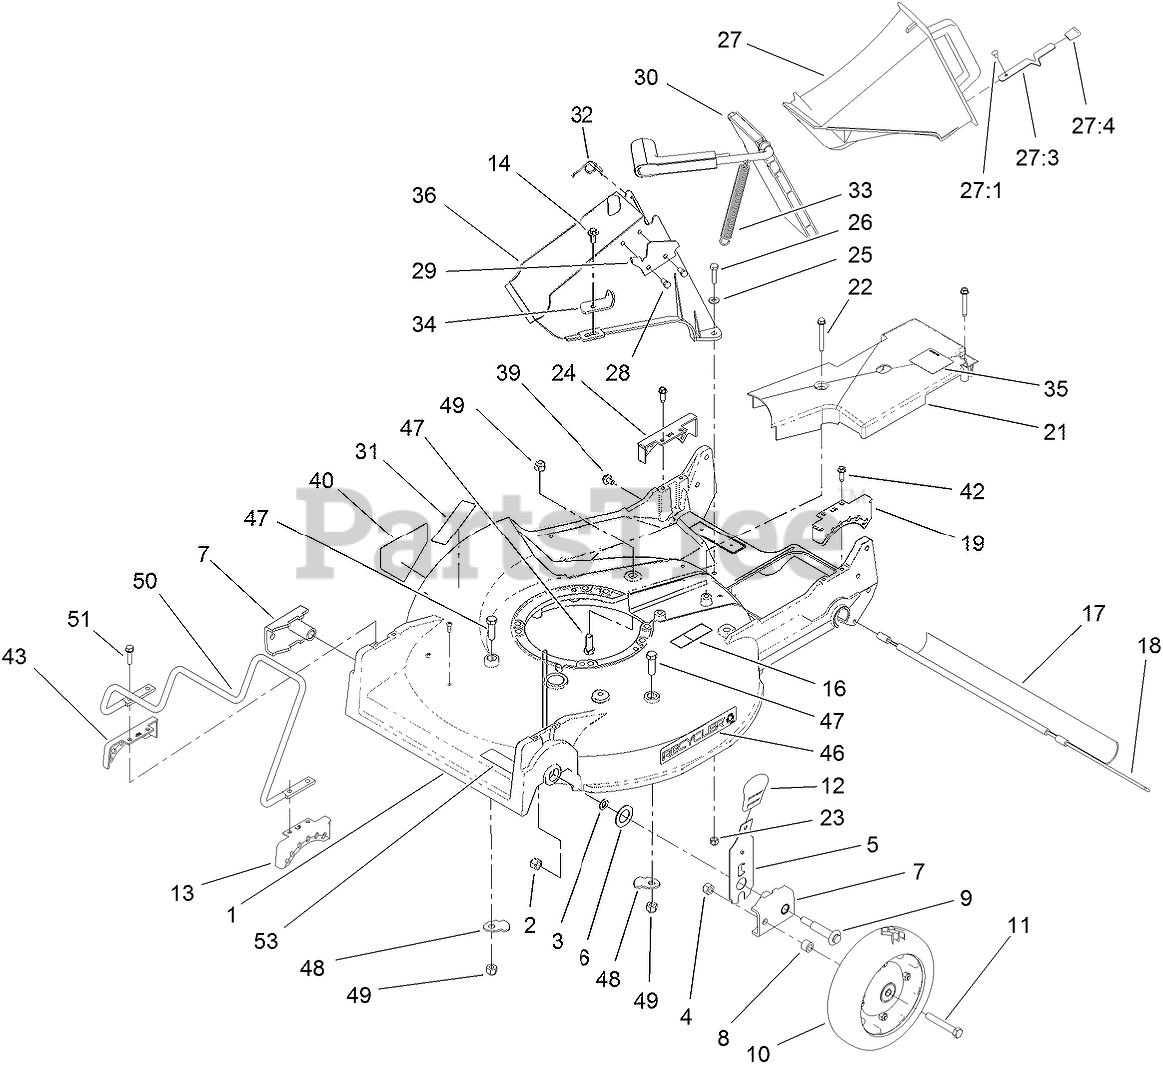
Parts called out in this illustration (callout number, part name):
1	HOUSING
2	NUT-LOCK
3	WASHER
4	NUT-LOCK, CONE
5	FRONT SPRING ARM ASM
6	WASHER-THRUST
7	ARM-PIVOT, FRONT
8	SPACER-WHEEL
9	SCREW-SHOULDER
10	WHEEL AND TIRE ASM
11	SCREW-HH
12	KNOB-HOC
13	QUADRANT-FRONT, LH
14	SCREW-HWH
16	DECAL-WARNING, BLOCK
17	SHIELD-TRAILING
18	ROD-SHIELD
19	QUADRANT-REAR, LH
21	COVER-BELT
22	SCREW-HWHTF
23	NUT-LOCK, NI
24	QUADRANT-REAR, RH
25	WASHER-FLAT
26	SCREW-HH
27	DISCHARGE PLUG ASM
27:1	RIVET-HEAD, FLAT
27:3	LATCH-PLUG, DISCHARGE
27:4	GRIP-LATCH
28	SCREW-PLASTITE
29	LATCH-PLATE
30	DISCHARGE DOOR ASM
31	DECAL-ARRESTER, SPARK
32	RETAINER-DOOR
33	SPRING-DOOR
34	BRACKET-SPRING
35	DECAL-GREASE
36	TUNNEL-DISCHARGE
39	SCREW AND WASHER ASM
40	DECAL-DANGER
42	SCREW-HWHTF
43	QUADRANT-FRONT, RH
47	SCREW-HH
48	SHIELD-RETAINER
49	NUT-LOCK, NI
50	GUARD-ENGINE
51	SCREW-HWHTF
53	DECAL-BLADE
